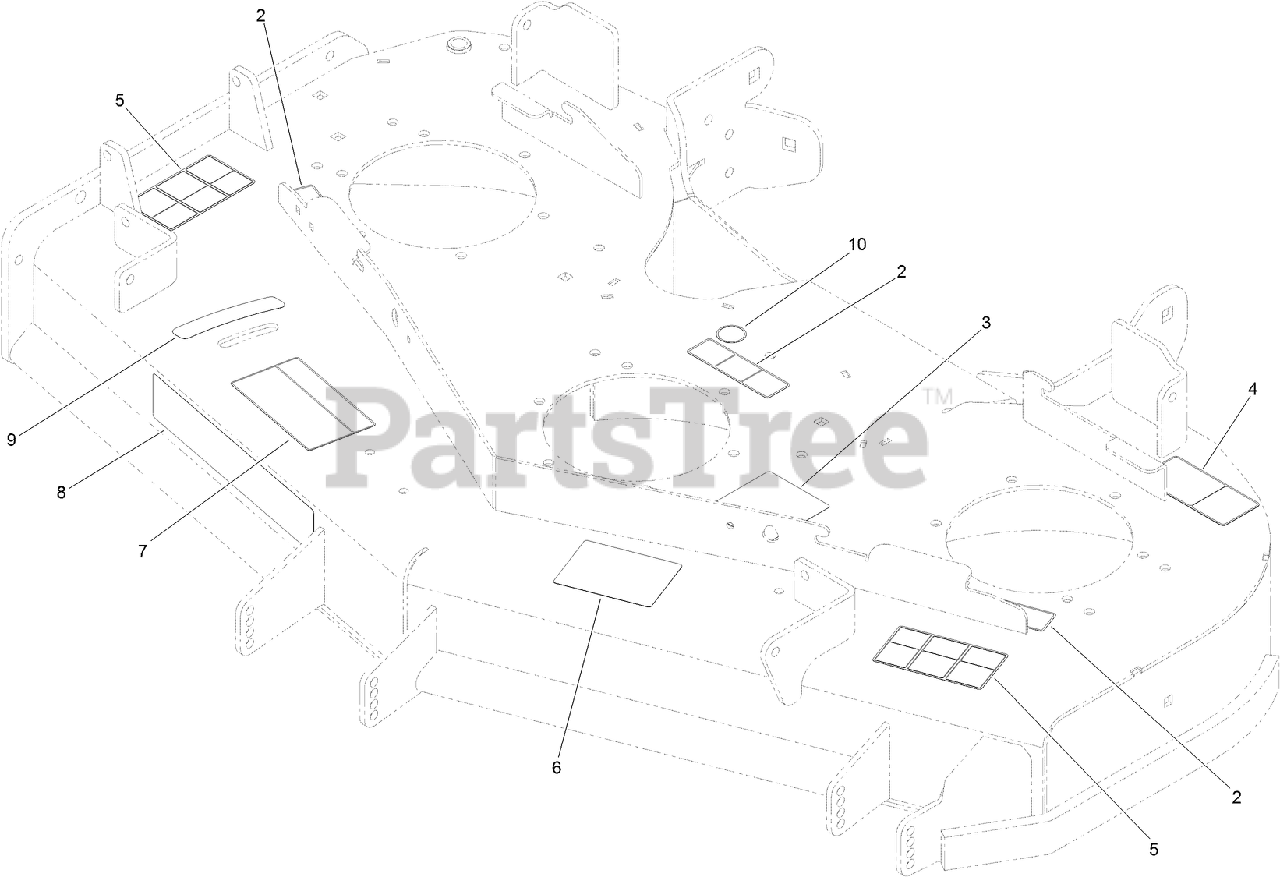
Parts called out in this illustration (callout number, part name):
2	DECAL-MISSING, COVER
3	DECAL-ROUTING, DECK BELT
4	DECAL-TORQUE, BLADE BOLT
5	DECAL-DANGER
6	DECAL-SCALP, ANTI
7	DECAL-ADJUSTMENT, BAFFLE
9	DECAL-SETTING, BAFFLE
10	DECAL-GREASE
